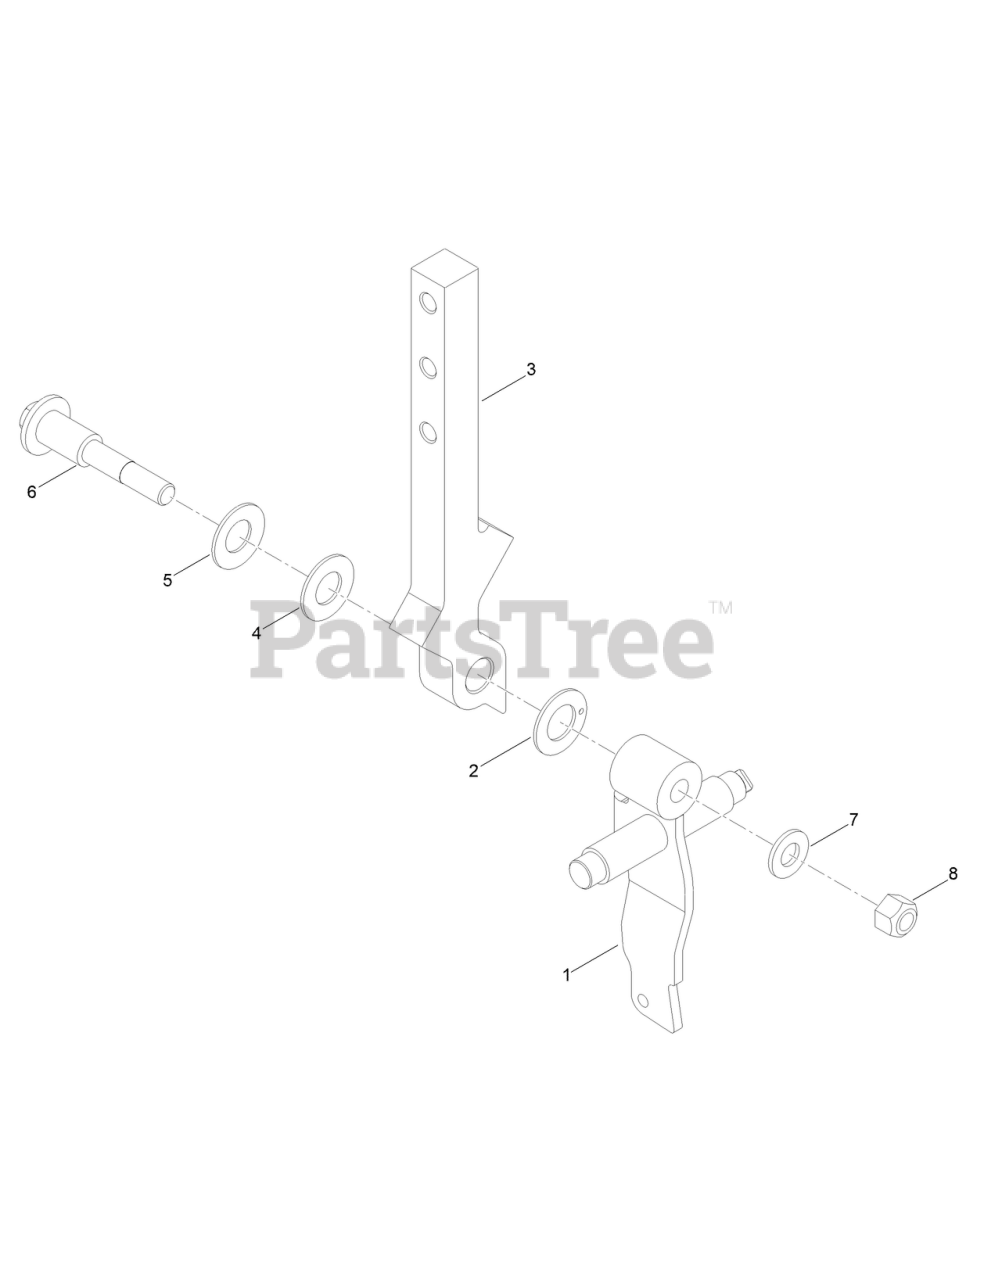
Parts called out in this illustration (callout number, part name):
1	ARM-CONTROL, RH
2	WASHER-FRICTION
3	ARM-CONTROL
4	WASHER
5	WASHER-BELLEVILLE
6	BOLT-PIVOT
7	WASHER-FLAT
8	NUT-LOCK, CONE
